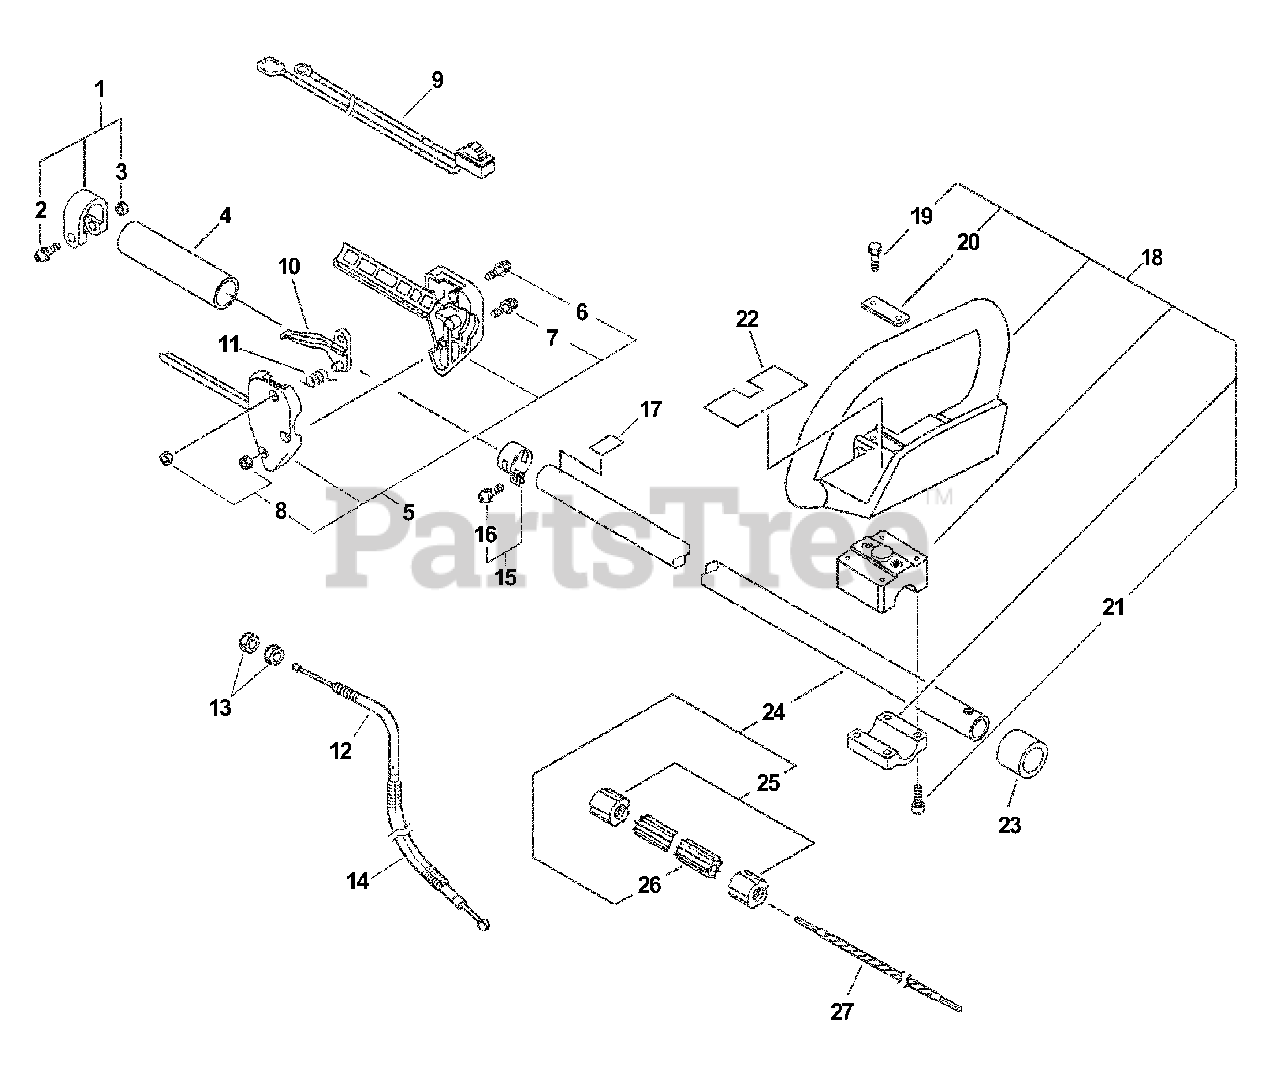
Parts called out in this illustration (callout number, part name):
1	CLAMP
2	SCREW - 5X28
4	GRIP, HANDLE - REAR
5	CONTROL HANDLE ASSY
6	SCREW - 5X35
7	SCREW - 5X25
9	IGNITION SWITCH ASSY
10	TRIGGER, THROTTLE
11	SPRING, TRIGGER
12	CABLE, THROTTLE
14	TUBE, PROTECTIVE - CORRUGATED
15	CLAMP KIT
16	SCREW - 5X14
17	LABEL - ALIGNMENT
18	HANDLE ASSY - FRONT
19	SCREW - 5X30
21	SCREW - 5
22	LABEL - WARNING
23	COLLAR
24	MAIN PIPE ASSY
26	LINER - FLEXIBLE
27	DRIVESHAFT - FLEXIBLE
